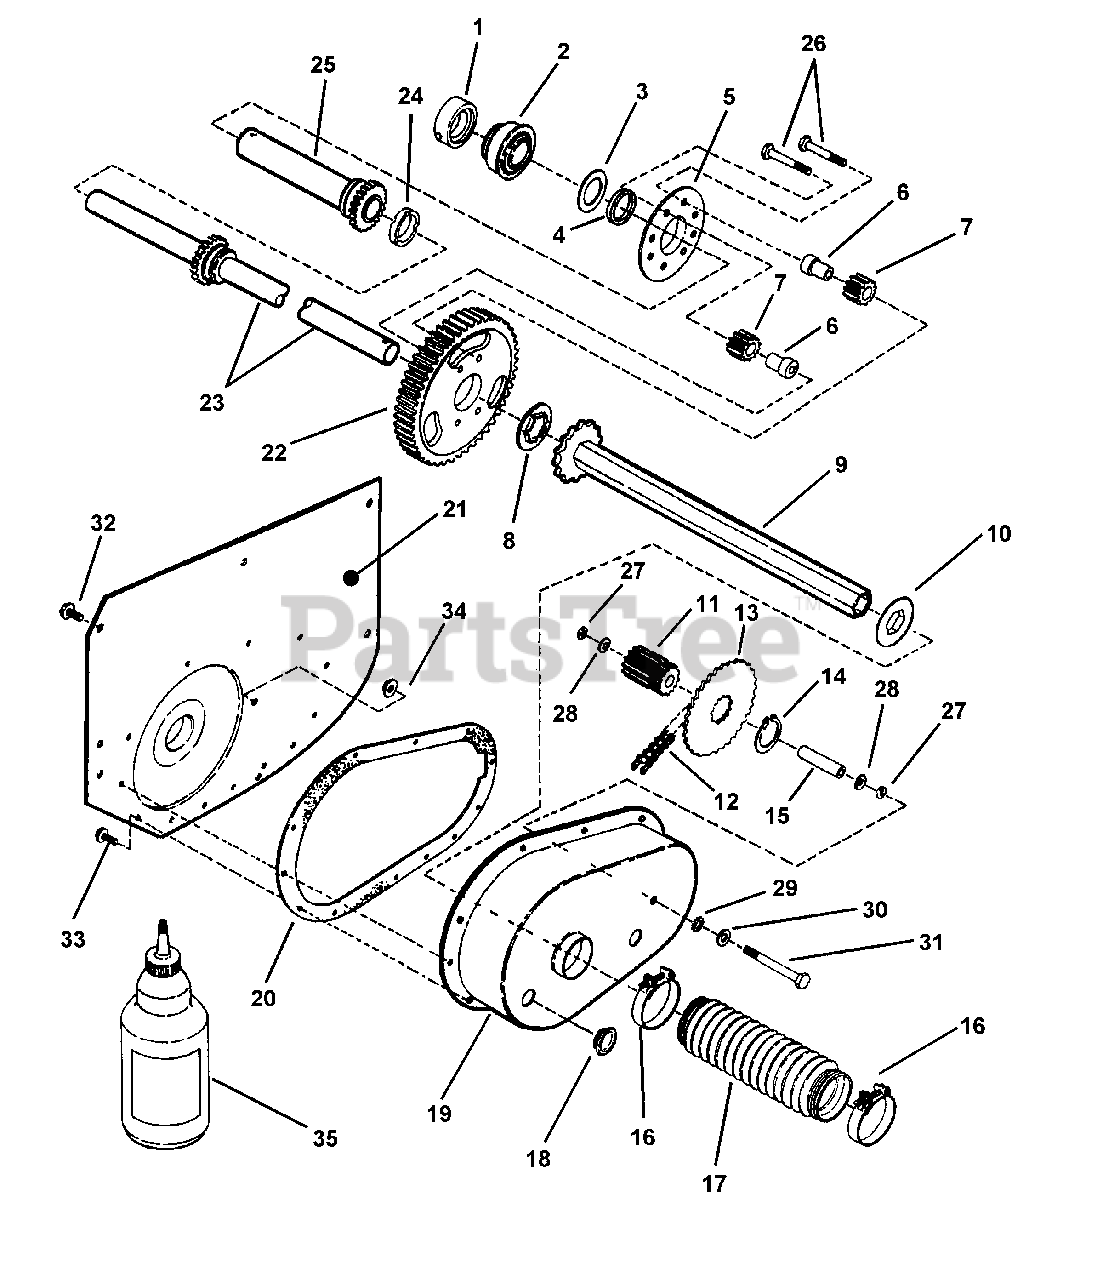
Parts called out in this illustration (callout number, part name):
1	COLLAR, Lock
2	BALL BEARING, Axle
3	WASHER, Thrust
4	SPACER, Short Axle
5	PLATE, Differential
6	SPACER, Pinion
7	GEARS, Differential Pinion
8	WASHER, Thrust
9	ASSEMBLY, Drive Hex Tube
10	WASHER, Hex Insert
11	GEAR, 11 Teeth-10 Pitch
12	CHAIN, 46 Pitch (#35)
13	SPROCKET
14	RING, 1-13/16" External Retaining
15	SPACER
16	CLAMP, Boot, 2"
17	BOOT, Oil Seal
18	PLUG, Oil Fill & Check
19	CASE, Transmission
20	GASKET, Transmission Case
21	FENDER, Right Hand (2.498" ID Hole)
22	GEAR, 63 Teeth-10 Pitch
23	AXLE, Long
24	SPACER, Differential (1.25" ID x .425 Wide)
25	AXLE, Short
26	SCREW, 5/16-24 x 1-5/8" Hex Cap Special Lock
27	O-RING, 5/16"
28	WASHER, Belleville
29	WASHER, 5/16" External Tooth Lock
30	WASHER, 5/16" Flat
31	BOLT, 5/16-24 x 2-5/8" Idler
32	SCREW, 5/16-18 x 5/8" Hex Washer Self-Tap
33	SCREW, 1/4-20 x 5/8" Hex Washer Self-Tap
34	NUT, 5/16-24 Hex Flange Lock
35	GREASE, SNAPPER Transmission
